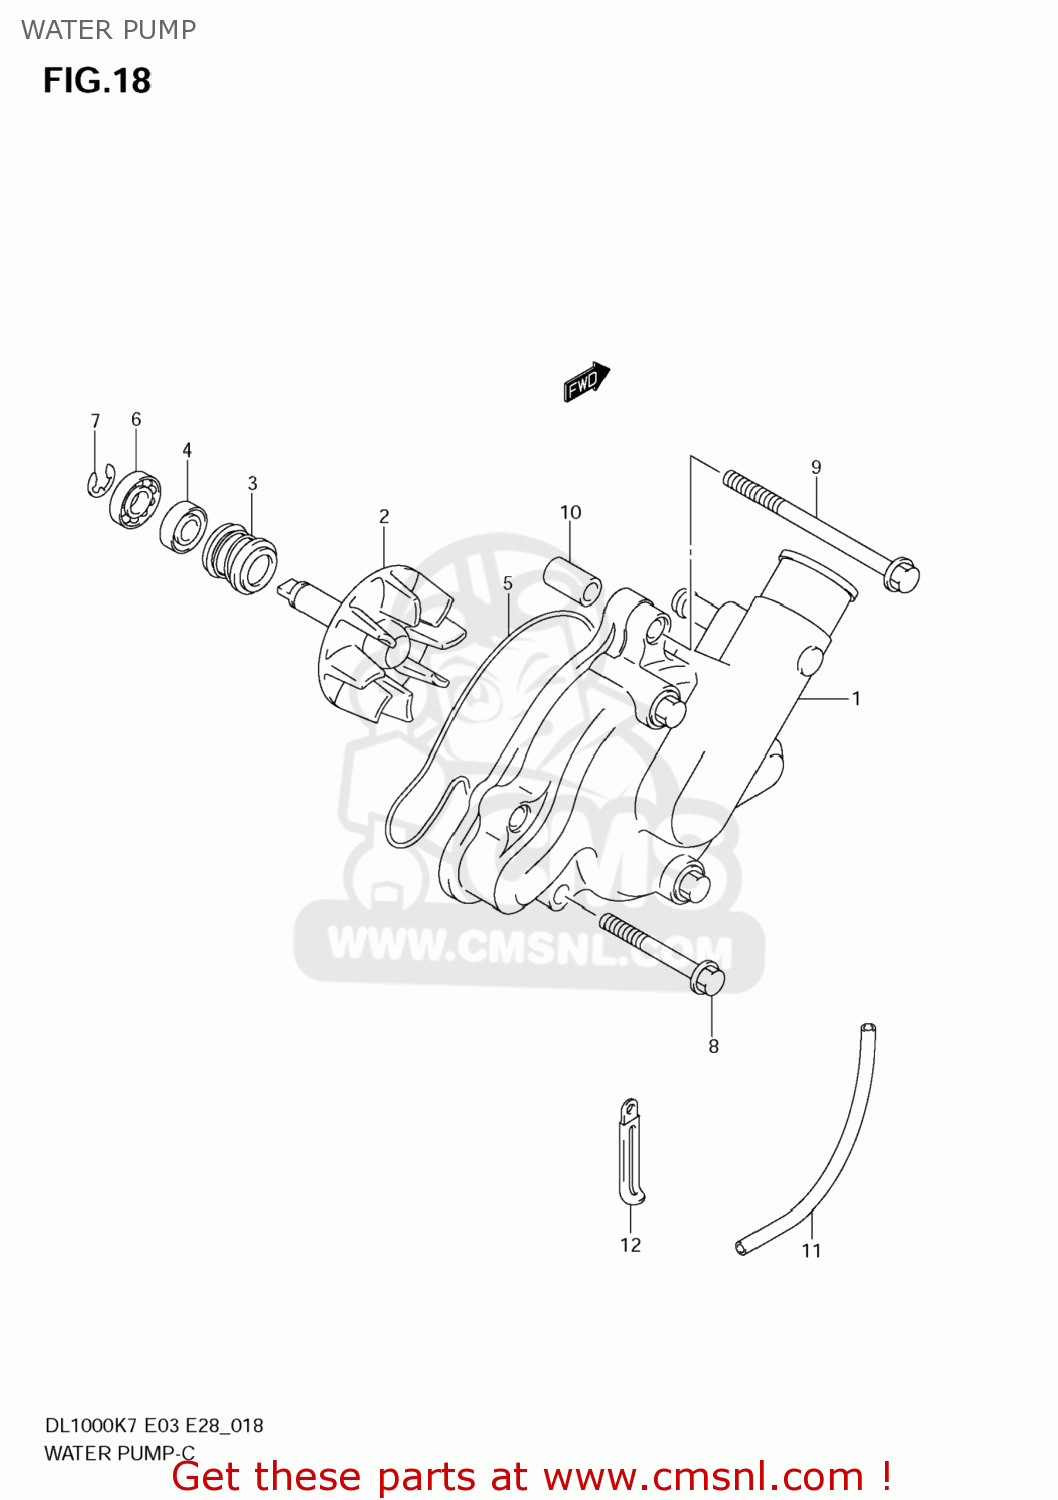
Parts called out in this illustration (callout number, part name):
1	CASE,WATER PUMP
2	IMPELLER,WATER PUMP
3	SEAL,MECHANICAL
4	SEAL,OIL(10X20X5)
5	O RING,WATER PUMP CASE
6	BEARING(10X22X5)
7	E RING
8	BOLT(6X30)
9	BOLT(6X65)
10	PIN
11	HOSE(4.2X7X600)
12	CLAMP(L:80)
